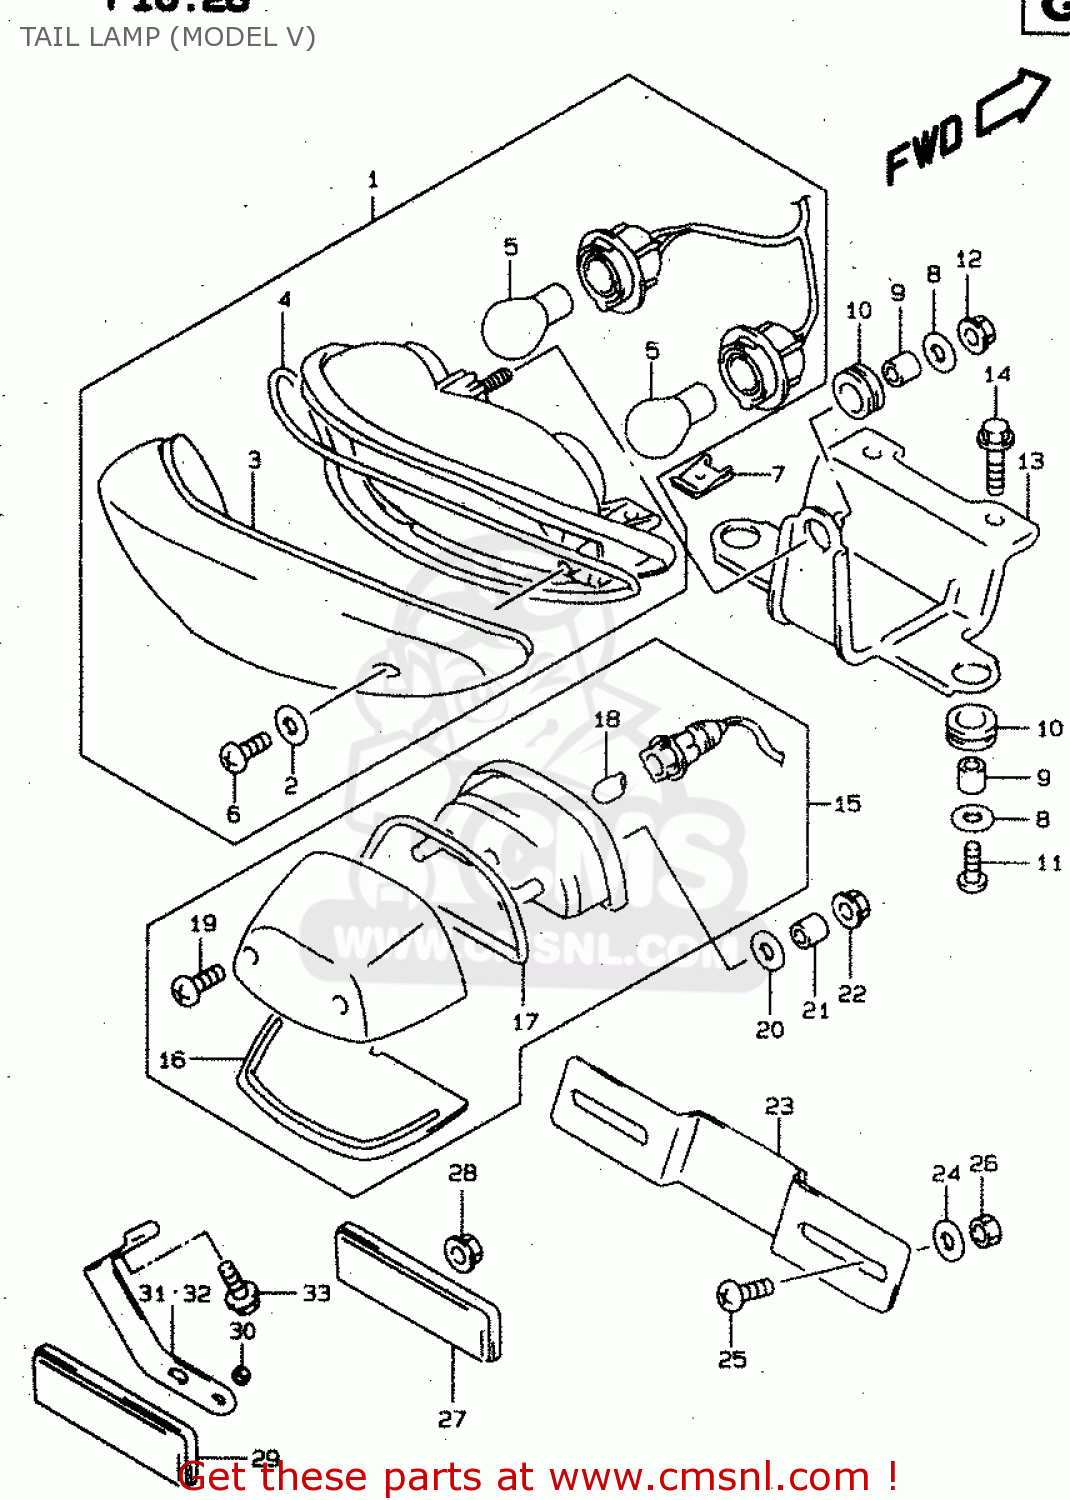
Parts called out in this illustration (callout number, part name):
1	LAMP ASSY,RR COMBINATION
2	GASKET (NAS)
3	LENS
4	GASKET (NAS)
5	BULB(12V21/5W)
6	SCREW
7	NUT
8	WASHER(6.5X20X1.6)
9	SPACER(6.5X10X9)
10	CUSHION
11	SCREW
12	NUT
13	BRACKET,RR COMBINATION LAMP
14	BOLT
15	LAMP ASSY,LICENSE
16	LENS
17	GASKET (NAS)
18	BULB(12V5W)
19	SCREW
20	WASHER(6.5X20X1.6)
21	SPACER(5.5X9.5X11.5)
22	NUT
23	BRACKET,LICENSE PLATE
24	WASHER(6.5X20X1.6)
25	SCREW 6X12
26	NUT
27	REFLECTOR ASSY,RR
28	NUT
29	REFLEX REFLECTOR,FR SIDE
30	NUT
31	BRACKET,RR SIDE RR,R
32	BRACKET,RR SIDE RR,L
33	BOLT
